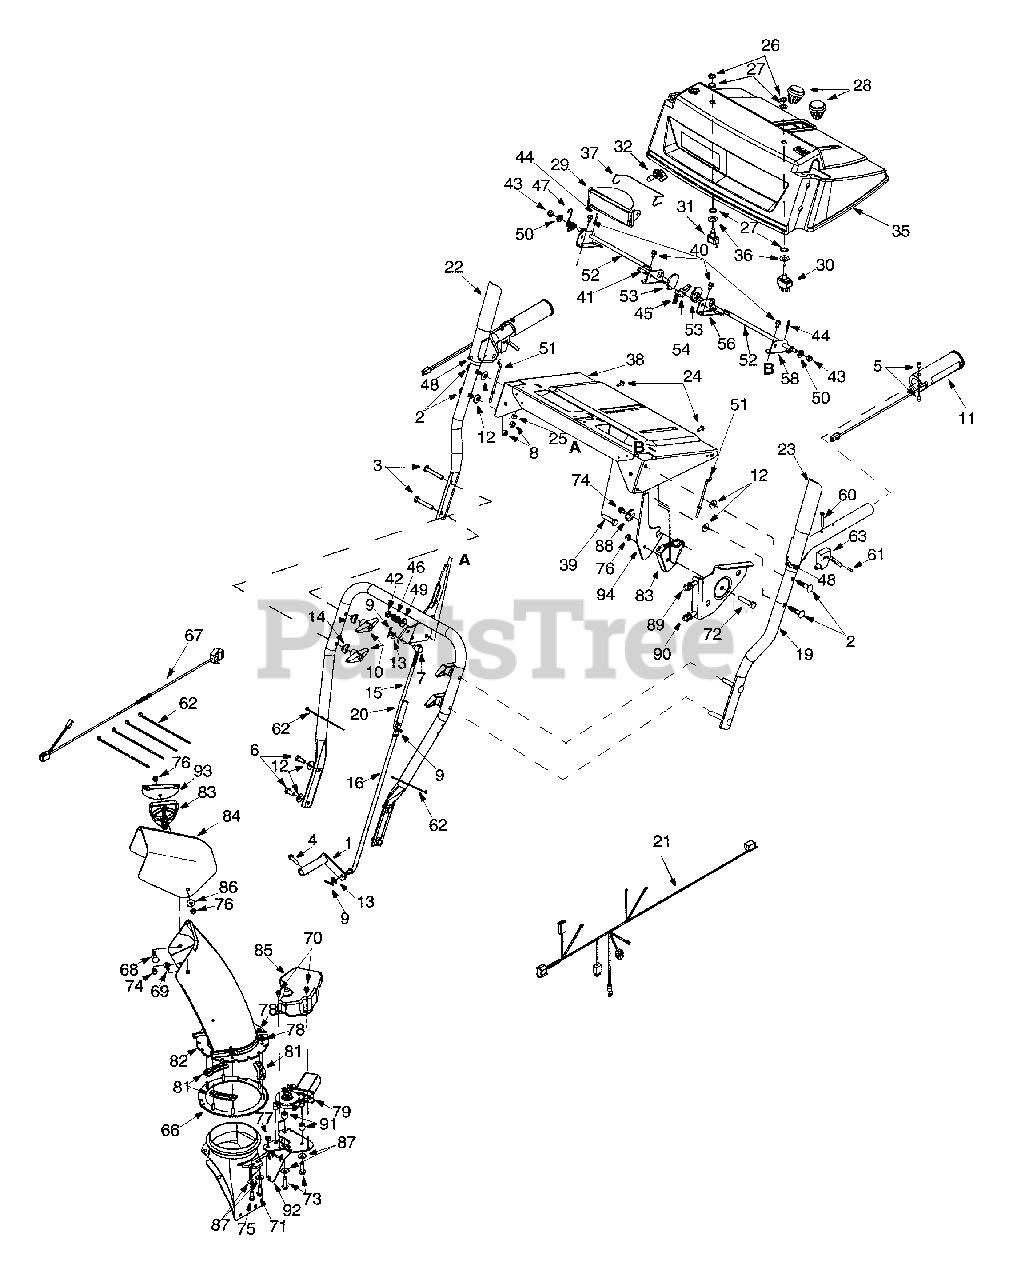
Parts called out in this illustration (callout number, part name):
2	Carriage Bolt: 5/16-18 x 1.5"
3	Carriage Screw 5/16-18 x 2.25
4	TT Screw 1/4-20 x 1.0"
5	Oval C-Sunk AB Screw
6	Hex Screw 5/16-18 x 0.75"
7	Ferrule
8	Hex Nut
9	Hairpin Clip
10	Wing Nut
11	Heated Grip
12	Lock Washer
13	Flat Washer
14	Saddle Washer
15	Upper Shift Rod
16	Lower Shift Rod
21	Harness Assembly: Chute Crank
22	Handle Engagement RH
23	Handle Engagement LH
24	Special Screw
25	Sems Nut
26	Hex Nut
27	Lock Ring: Toggle Switch
28	Shift Knob
29	Lamp Housing
30	Toggle Switch: 2 Pos., Dbl. Throw
31	Toggle Switch: 2 Pos., Sngl. Throw
32	Halogen Lamp
35	Handle Panel
36	Flat Washer
37	Headlight Retainer
39	Hex Screw: Special
40	TT Screw: 1/4-20 x 0.5"
41	Clevis Pin
42	Jam Lock Nut
43	Hex Lock Nut
44	Hairpin Clip
45	Compression Spring
46	Compression Spring
47	Torsion Spring
48	Rubber Bumper
49	Spring Washer
50	Special Washer
51	Z Fitting
52	Cam Rod
53	Cam Handle Lock
54	Pawl: Handle Lock
60	Oval C-Sunk Machine Screw
61	Flange Weld Nut
62	Cable Tie
63	Control Trigger
66	Gear Assembly: Ring: Chut Rotatn.
67	Harness Assembly: Lower
68	Carriage Bolt: 5/16-18 x 1.5"
69	Carriage Bolt: 5/16-18 x .750"
70	TT Screw 1/4-20 x 0.5"
71	TT Screw 5/16-18 x 1.0"
72	Hex Screw 5/16-18 x 1.5"
73	TT Screw 5/16-18 x 1.0"
74	AB Screw
75	Hex Bolt 5/16-18 x 0.75"
76	Lock Nut
77	Hex Nut 5/16-18
78	Flange Lock Nut
79	Electric Motor: Chute Crank
81	Flange Keeper
82	Lower Chute
83	Cable Guide: Chute Tilt
84	Upper Chute
85	Motor Cover
86	5/16 Washer
87	Beleville Washer
88	Special Washer
89	Chute Cable
90	Cable: Chute Deflector w/Clip
91	Spacer
